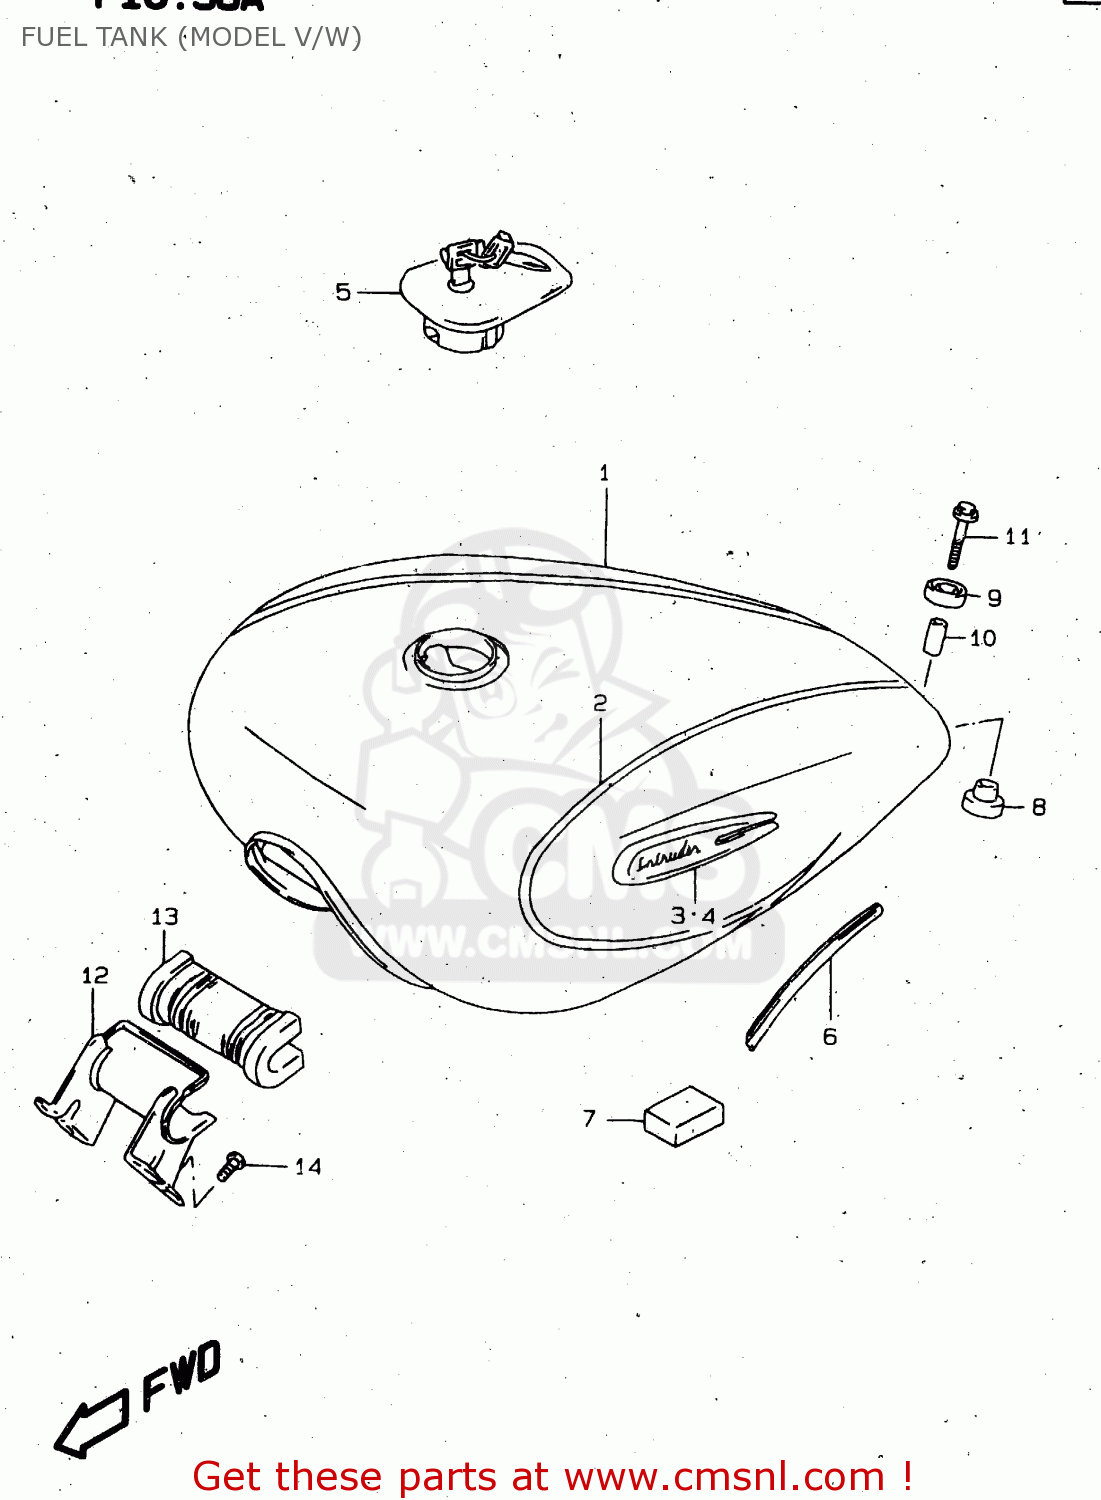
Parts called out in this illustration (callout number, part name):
1	TANK ASSY,FUEL
2	TAPE SET,FUEL TANK
3	EMBLEM,FUEL TANK,R
4	EMBLEM,FUEL TANK,L
5	CAP SET,FUEL TANK
6	MOLDING
7	CUSHION
8	CUSHION
9	CUSHION
10	SPACER(6.5X9X22.5)
11	BOLT
12	BRACKET,TANK
13	CUSHION,FUEL TANK FR
14	SCREW
